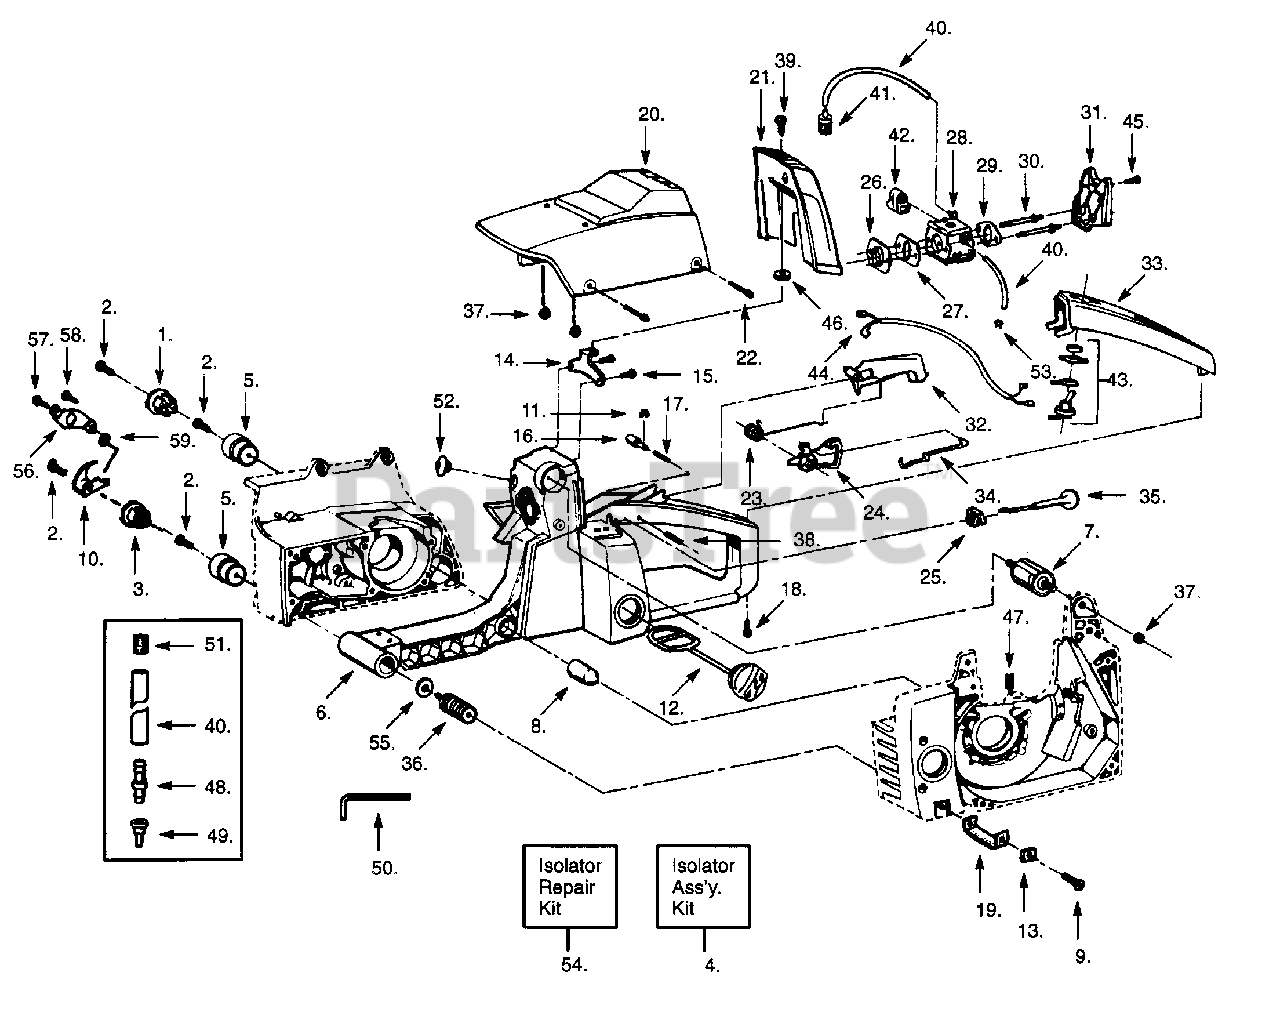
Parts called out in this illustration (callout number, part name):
1	Retainer Mount
3	Chain Catcher Retainer
4	Isolator Ass'y. Kit
5	Lower Isolator
6	Rear Handle & Fuel Tank
7	Cylindrical Mount
8	Isolator Limiter
9	Screw
10	Chain Catcher
11	"C" Clip
12	Fuel Cap Ass'y.
13	Strap Retainer Plate
16	Throttle Lock
17	Throttle Lock Spring
19	AV Strap
20	Cylinder Shield Kit
21	Carb. Cover
22	Screw
23	Trigger Latch Spring
24	Throttle Trigger
27	Model 336C
27	Model 365C
28	Carburetor (HDA-49)
29	Air Filter Plate
30	Carb. Mounting Stud
31	Air Filter Ass'y.
32	Throttle Lockout
33	Rear Handle Cover
34	Throttle Wire
35	Choke Knob
36	Spring Ass'y.
38	Dowel Pin
40	Line Kit (Bulk 530-008133)
41	Fuel Filter Ass'y.
43	Switch Kit
44	Lead Wire Ass'y.
45	Screw
46	Screw Retainer
47	Impulse Fitting
48	Vent Fitting
49	Check Valve
50	Hex Key
51	Vent Plug
52	Air Box Plug
54	Isolator Repair Kit
56	Bracket Retainer
58	Screw
59	Starting Inst. Decal
